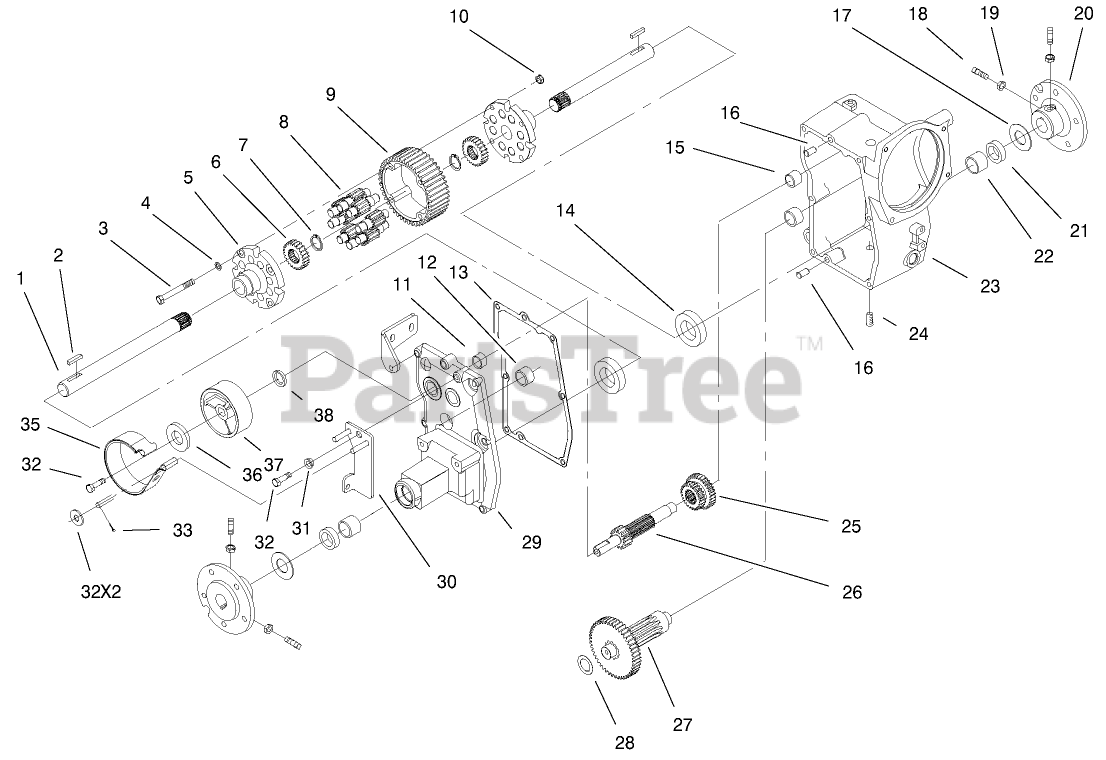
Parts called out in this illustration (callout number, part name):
1	AXLE-REAR
4	WASHER
5	END CAP-DIFFERENTIAL
6	GEAR-AXLE DIFFERENTIAL
7	RING-SNAP
8	GEAR-PINION, 11T
9	GEAR-DIFFERENTIAL RING, 43T
10	NUT-HEX
11	BEARING-NEEDLE
13	GASKET-CASE
14	BEARING-BALL
15	BEARING-NEEDLE
16	PIN-LOCATING
17	WASHER-THRUST
18	SCREW-SET, SQH
19	NUT-JAM
20	HUB-WHEEL
21	SEAL-OIL
22	BEARING
24	PLUG-PIPE
25	GEAR-SLIDING
26	SHAFT-BRAKE
27	GEAR ASM
28	WASHER-THRUST
30	ARM-PIVOT, BRAKE (BLACK)
31	CAM-SPACER
32	SCREW-HH, LOCK
33	PIN-COTTER
34	WASHER-FLAT
35	BAND-BRAKE
36	WASHER
37	DRUM-BRAKE
38	SEAL-OIL
